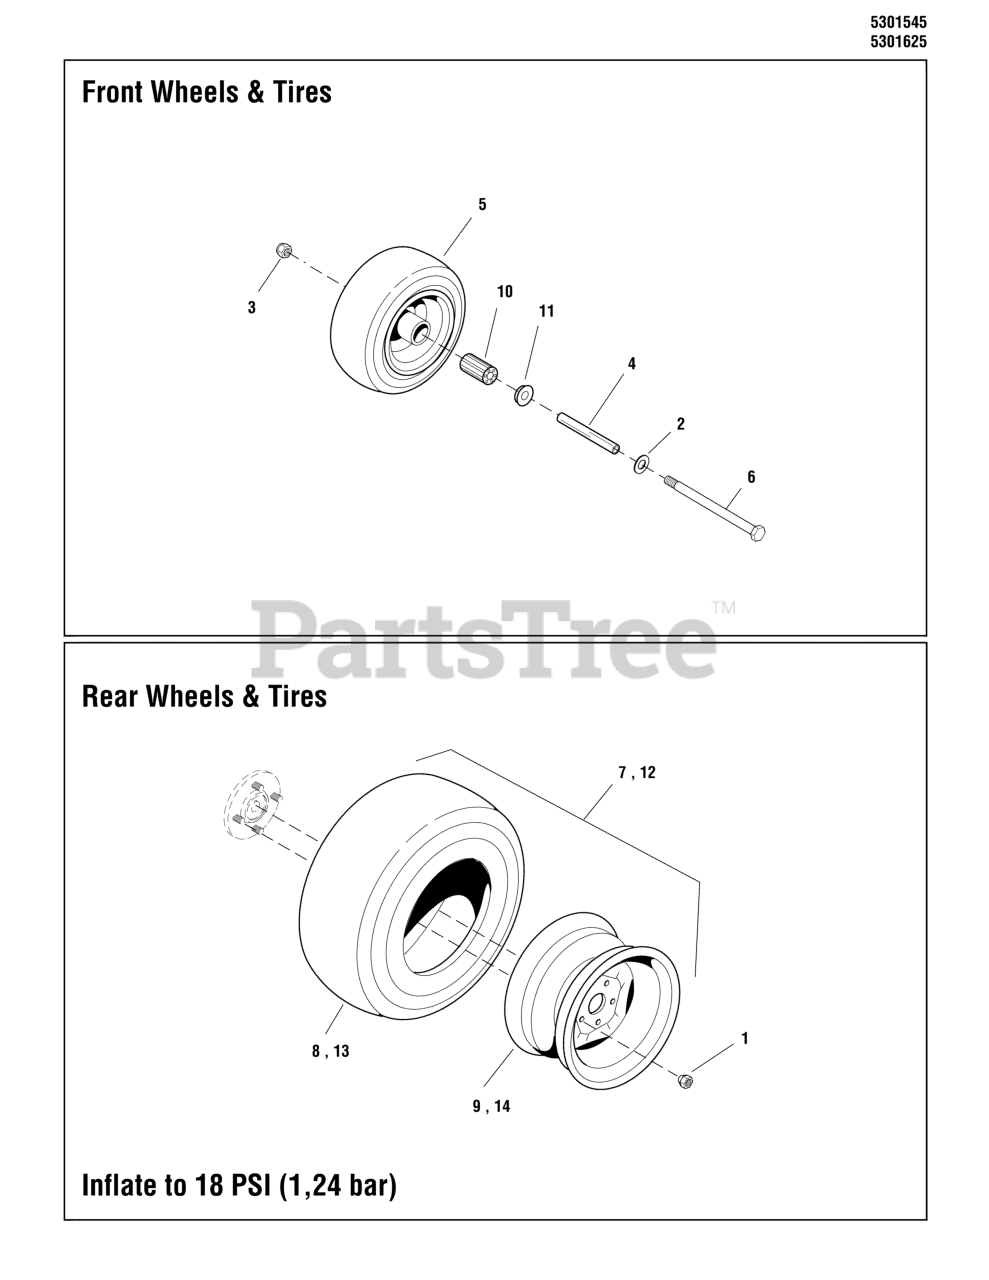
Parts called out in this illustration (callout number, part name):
1	NUT, 1/2-20, FOR WHEEL BOLT SILVER
2	WASHER, 1/2 SAE
3	NUT, Hex Flange, Nylock, 1/2-13
4	CASTER AXLE DDSH
5	TIRE/WHEEL ASSM 11/4.00-5 FLAT FREE
6	BOLT, HEX, 1/2-13 X 7, GD 8, YZ
7	TIRE ASSM, 18 X 8.5 X 10
8	TIRE, 18 X 8.5 X 10
9	RIM, 10 X 7, 4/4 BOLT CIRCLE, 2.625 POS
10	BEARING, CASTER WHEEL
11	BEARING, RETAINER
12	TIRE/WHEEL ASM, 22X10.00 - 10 TURF MASTE
13	TIRE, 22 X 10 X 10
14	WHEEL, 22 X 10 X 10
